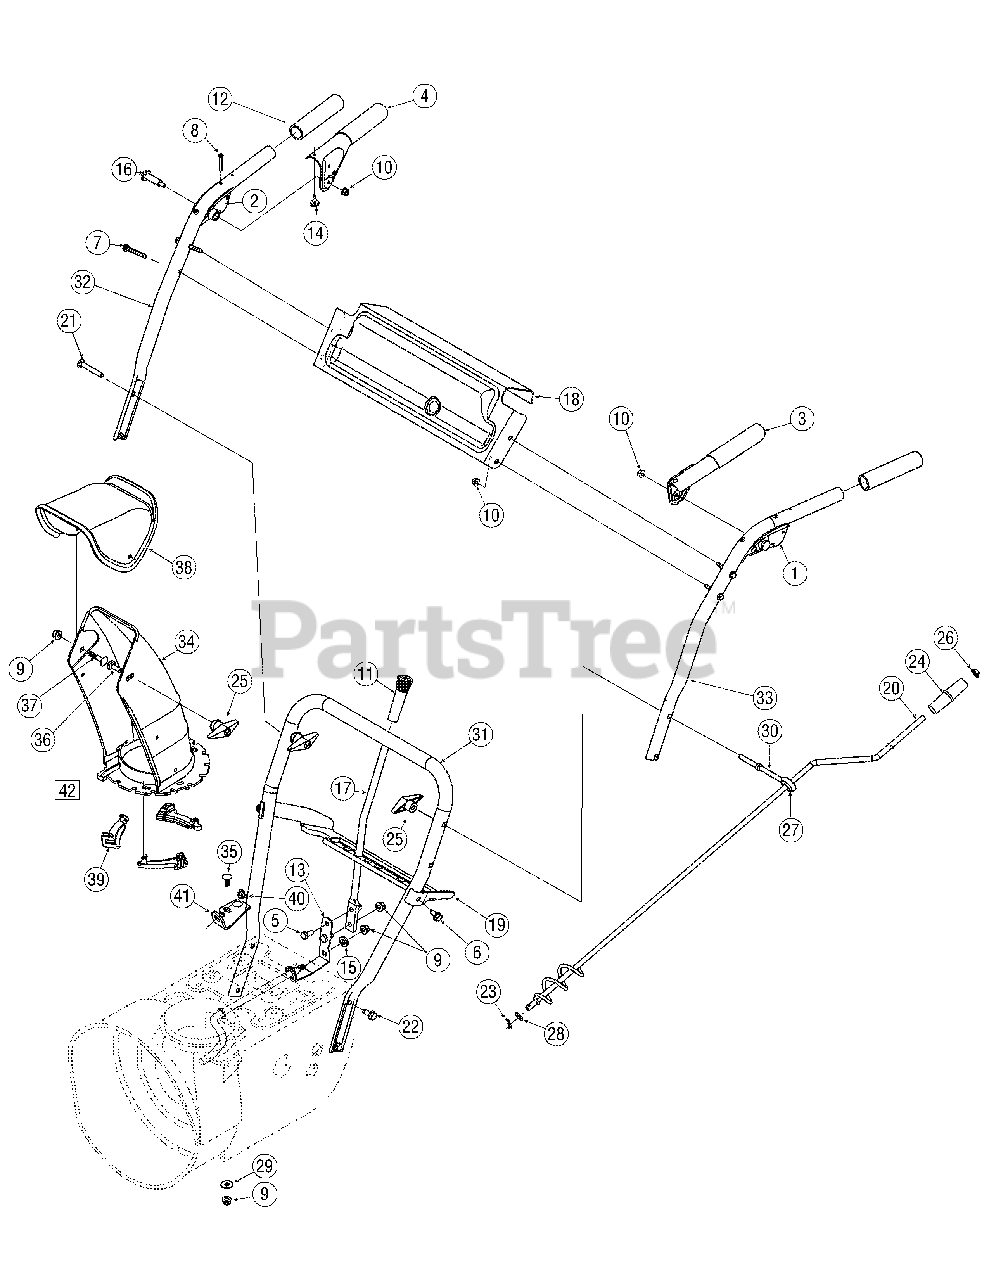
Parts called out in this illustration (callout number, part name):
1	Handle Ass’y, Lock LH
2	Handle Ass’y, Lock, RH
3	Handle Ass’y, Engagement LH
4	Handle Ass’y, Engagement, RH
5	Screw, Self-tapping, 5/16-18, .625
6	Screw, Self-tapping, 5/16-18, .750
7	Screw, Self-tapping, 1/4-20, 1.50
8	Screw, Machine, #10-24, 1.375
9	Nut, Flange Lock, 5/16-18, Nylon
10	Nut, Flange Lock, 1/4-20, Nylon
11	Grip, 0.5 ID x 3.45
12	Grip, 1.0 ID x 5.0
13	Spring Lever, Shift
14	Bumper, Rubber, .62 OD x .22
15	Washer, Flat, .469 x .875 x .105
16	Screw, Shoulder, 1/4-20, .437
21	Screw, Carriage, 5/16-18, 2.25
22	Screw, 5/16-18, 2.25, Gr5
23	Pin, Cotter, .072 x 1.13
24	Crank Knob, 1.0 Dia. x 3.2, Black
25	Knob Assembly, Black, 5/16-18
26	Cap, Push, 3/8 Rod
27	Grommet, .44 ID x .94 OD x .50
28	Washer, Flat, .375 x .738 x .063
29	Washer, Flat, .349 x .879 x .063
30	Eye Bolt, Chute Crank
34	Chute, Lower, 5.0 Diameter
35	Bolt, Carriage, 5/16-18, 1.0
36	Bolt, Carriage, 5/16-18, 1.0
37	Bolt, Carriage, 5/16-18, .750
38	Chute, Upper, w/ Label
39	Chute, Flange Keeper
40	Bushing, Plastic, .380
42	Chute Assembly (Includes Ref. # 39)
